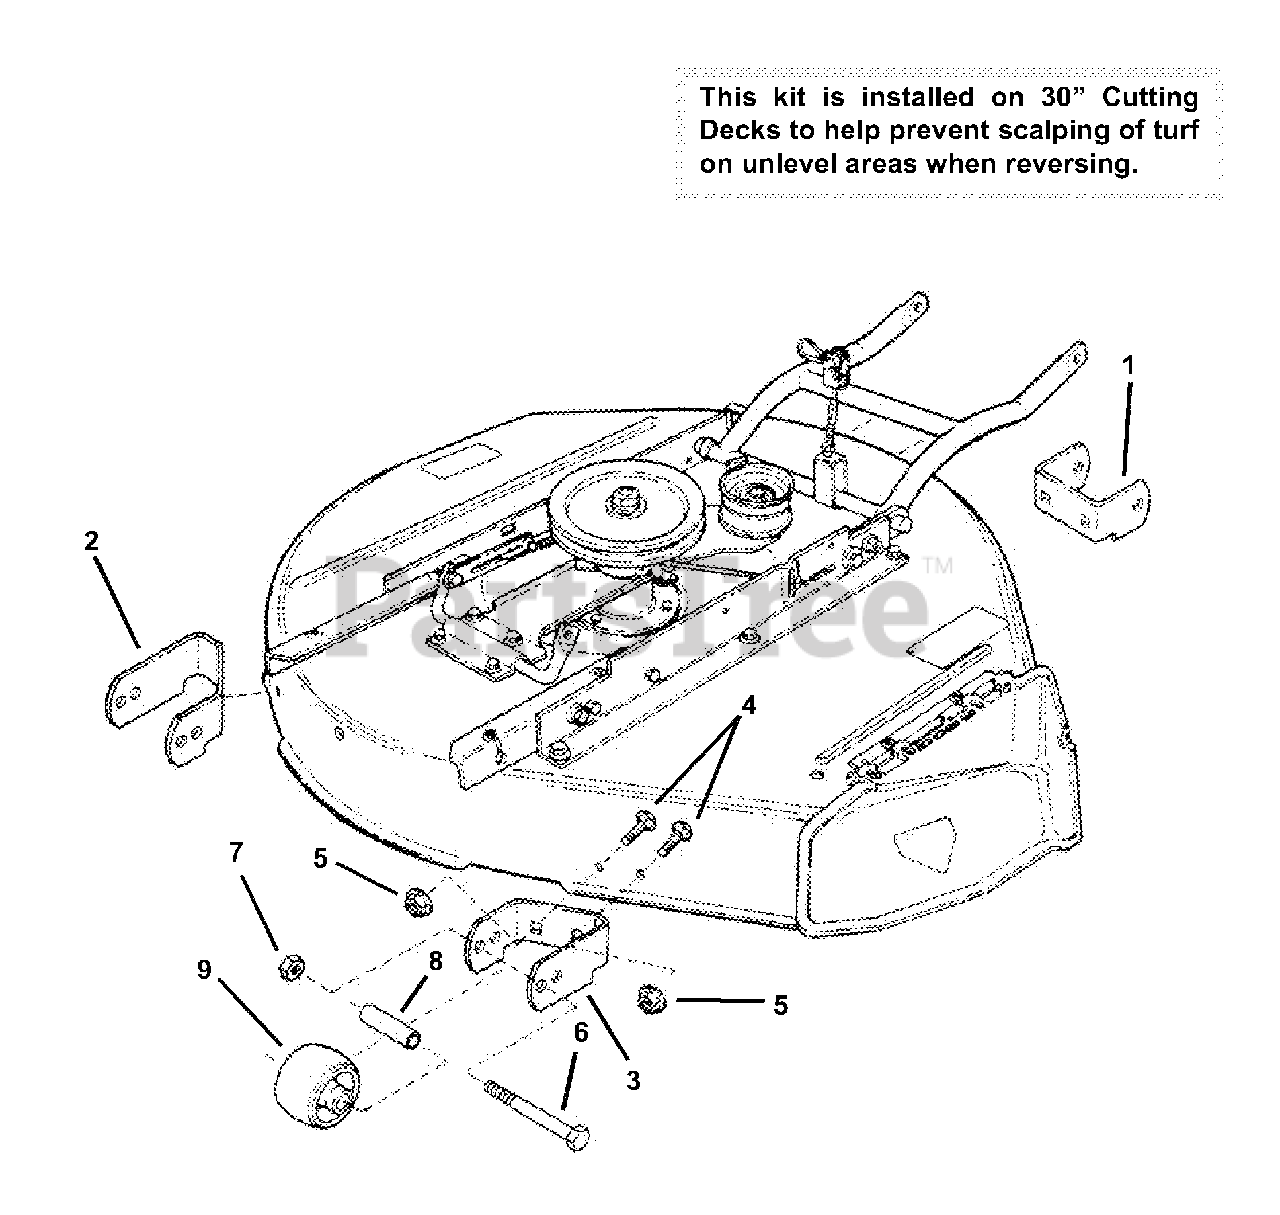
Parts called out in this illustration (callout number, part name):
1	BRACKET, Front Anti-Scalp
2	BRACKET, Left Anti-Scalp
3	BRACKET, Right Anti-Scalp
4	BOLT, 5/16-18x 1/2" Carriage
5	NUT, 5/16-18 Hex Flange Lock
6	SCREW, 3/8-24 x 3-3/4" HHC
7	NUT, 3/8-24 Hex Center Lock
8	SPACER
9	ROLLER
